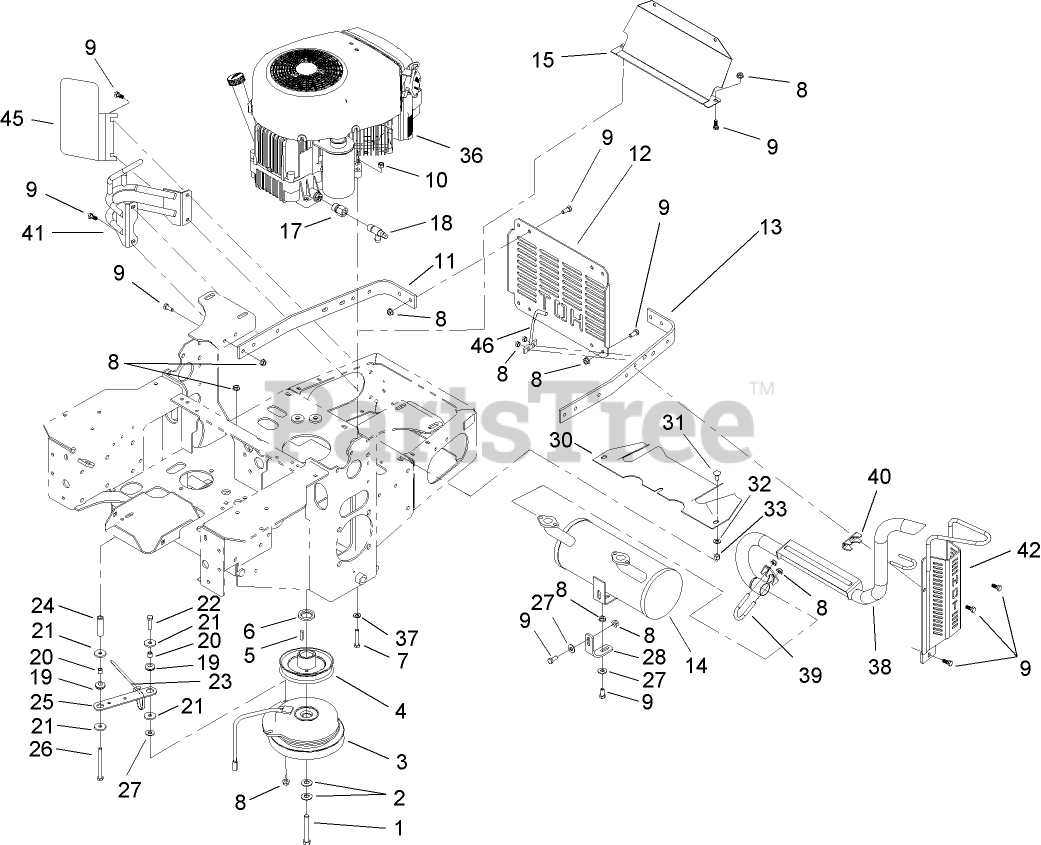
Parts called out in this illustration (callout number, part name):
1	SCREW-HH
2	WASHER-SPRING
3	CLUTCH
4	PULLEY
6	Spacer-Crankshaft
7	SCREW-HH
8	NUT-HF
9	SCREW-HH
10	NUT-LOCK, NI
11	STRAP-GUARD, RH
12	SHIELD-ENGINE
13	STRAP-GUARD, LH
14	Muffler
15	Shield-Heat
17	Adapter
18	Valve-Drain, Oil
19	GROMMET
20	SPACER
21	WASHER
22	SCREW-HH
23	TIE-PLASTIC
24	Spacer
25	STRAP-CLUTCH, BRAKE
26	SCREW-HH
27	WASHER-FLAT
28	BRACKET-SUPPORT, MUFFLER
30	SHIELD-HEAT
31	BOLT-CARR
32	WASHER-PLAIN
33	NUT-LOCK, NI
37	WASHER-SPRING
38	TAILPIPE
41	RH Exhaust Guard ASM
42	LH EXHAUST GUARD ASM
45	RH EXHAUST GUARD ASM
46	LH REAR GUARD ASM
